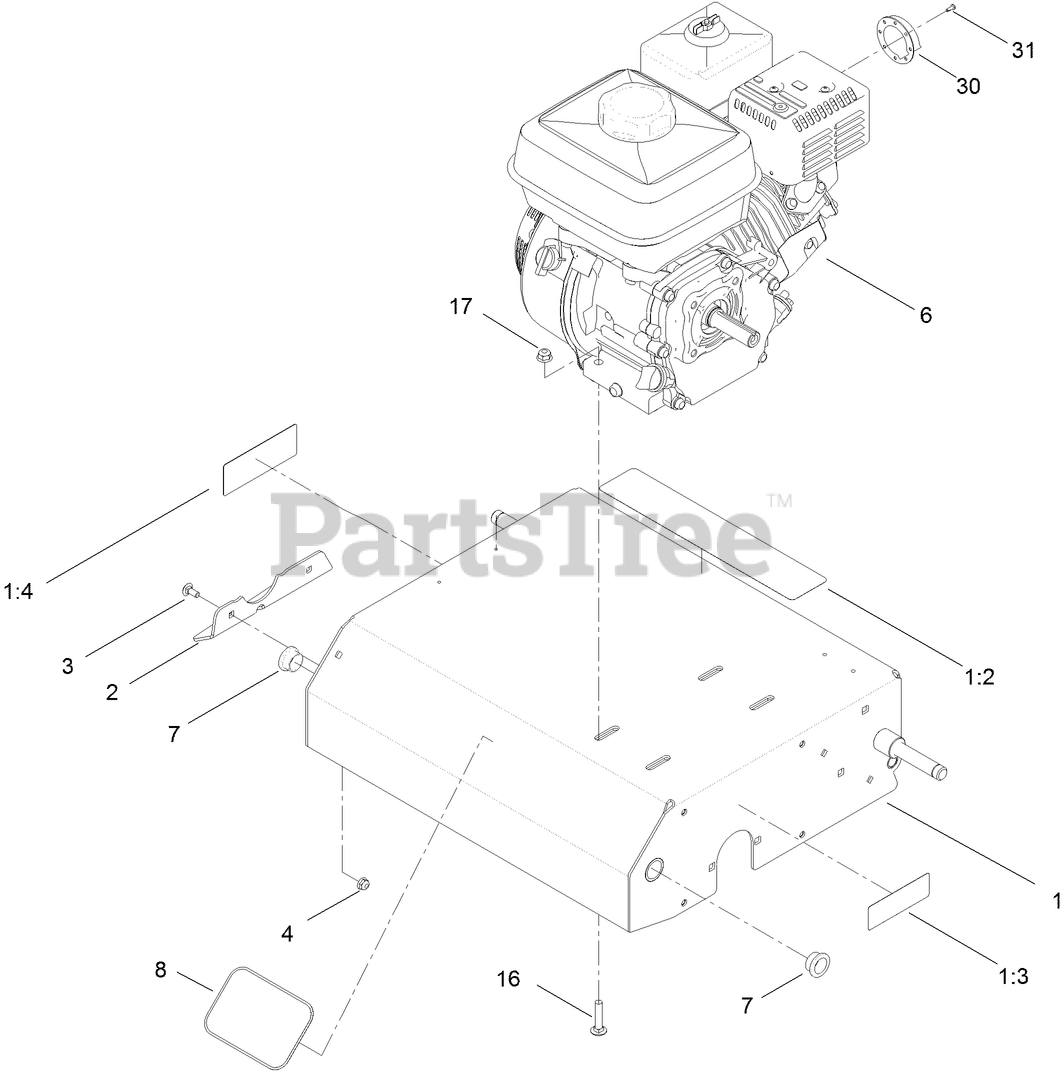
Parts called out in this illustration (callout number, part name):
1	FRAME ASM
1:2	DECAL-WARNING
1:3	DECAL-WARNING, SHIELDS
1:4	DECAL-DANGER
2	GUARD-HAND
3	SCREW-CARR
4	NUT-HF
7	BUSHING
8	DECAL
16	BOLT-CARR
17	NUT-HF, NI
30	DEFLECTOR
31	SCREW-PPHTF
